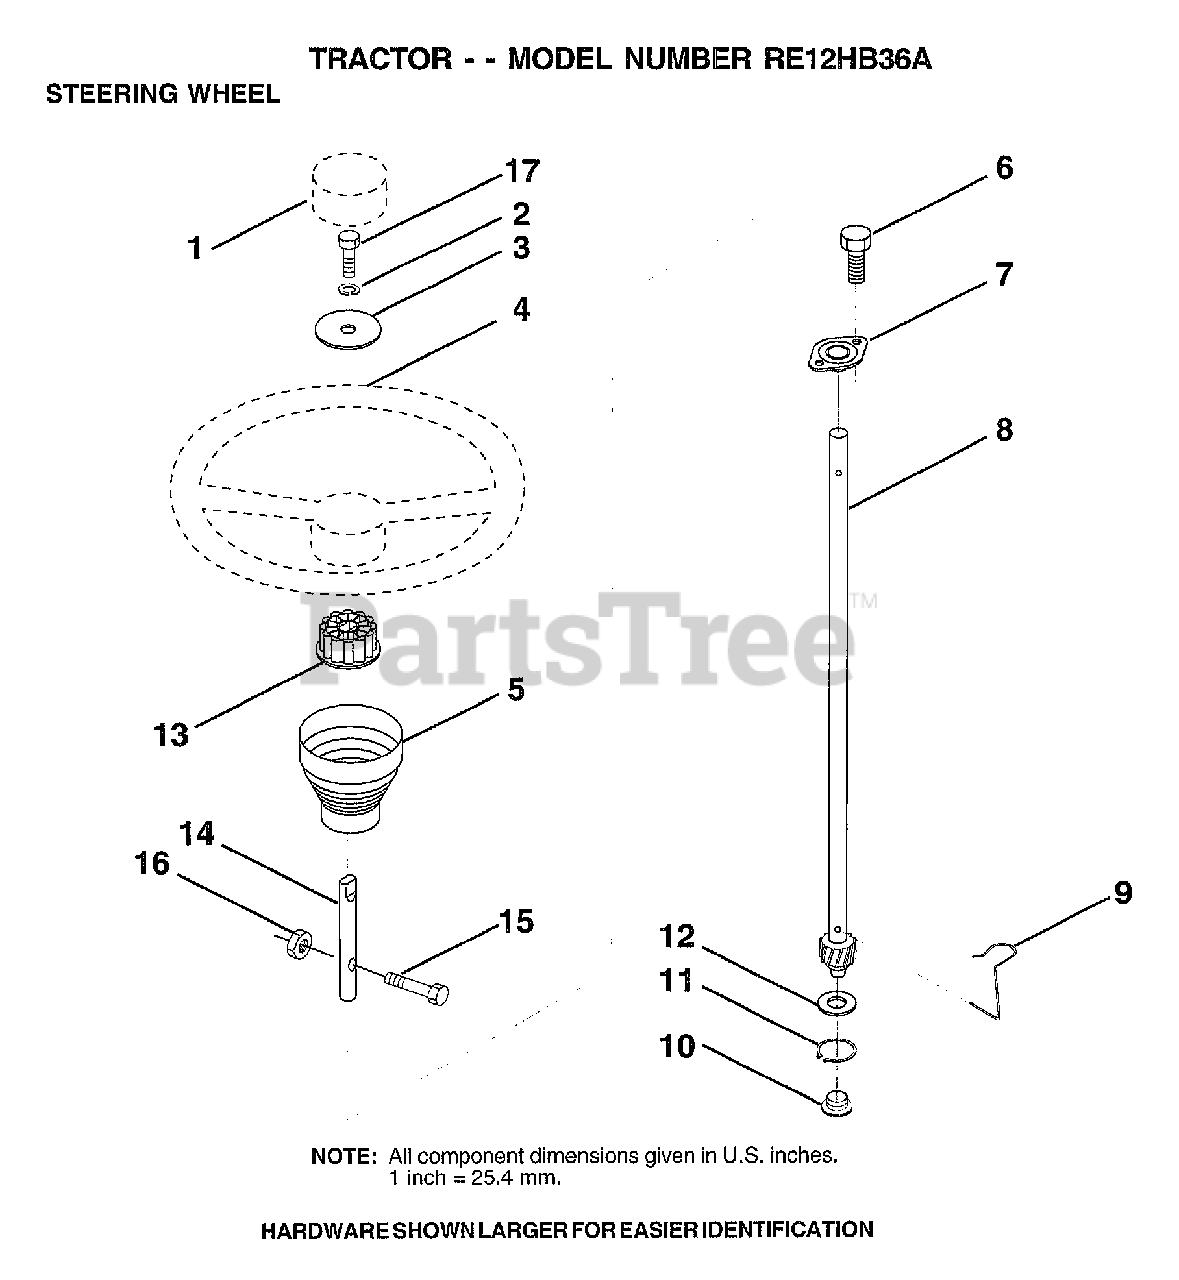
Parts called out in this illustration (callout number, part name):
1	ST WHL INSERT CAP
2	LOCKWASHER
3	WASHER
5	BOLT
6	"SCREW-TT,10-32 FL"
7	BUSHING.STR.623
8	SHAFT.STEERING.LR
9	STEERING CLIP
10	BUSHING STEER LWR
11	RING
12	WASHER LT
13	ADAPTER LT
14	EXT SHAFT STEERIN
15	BOLT
16	NUT
17	BOLT
